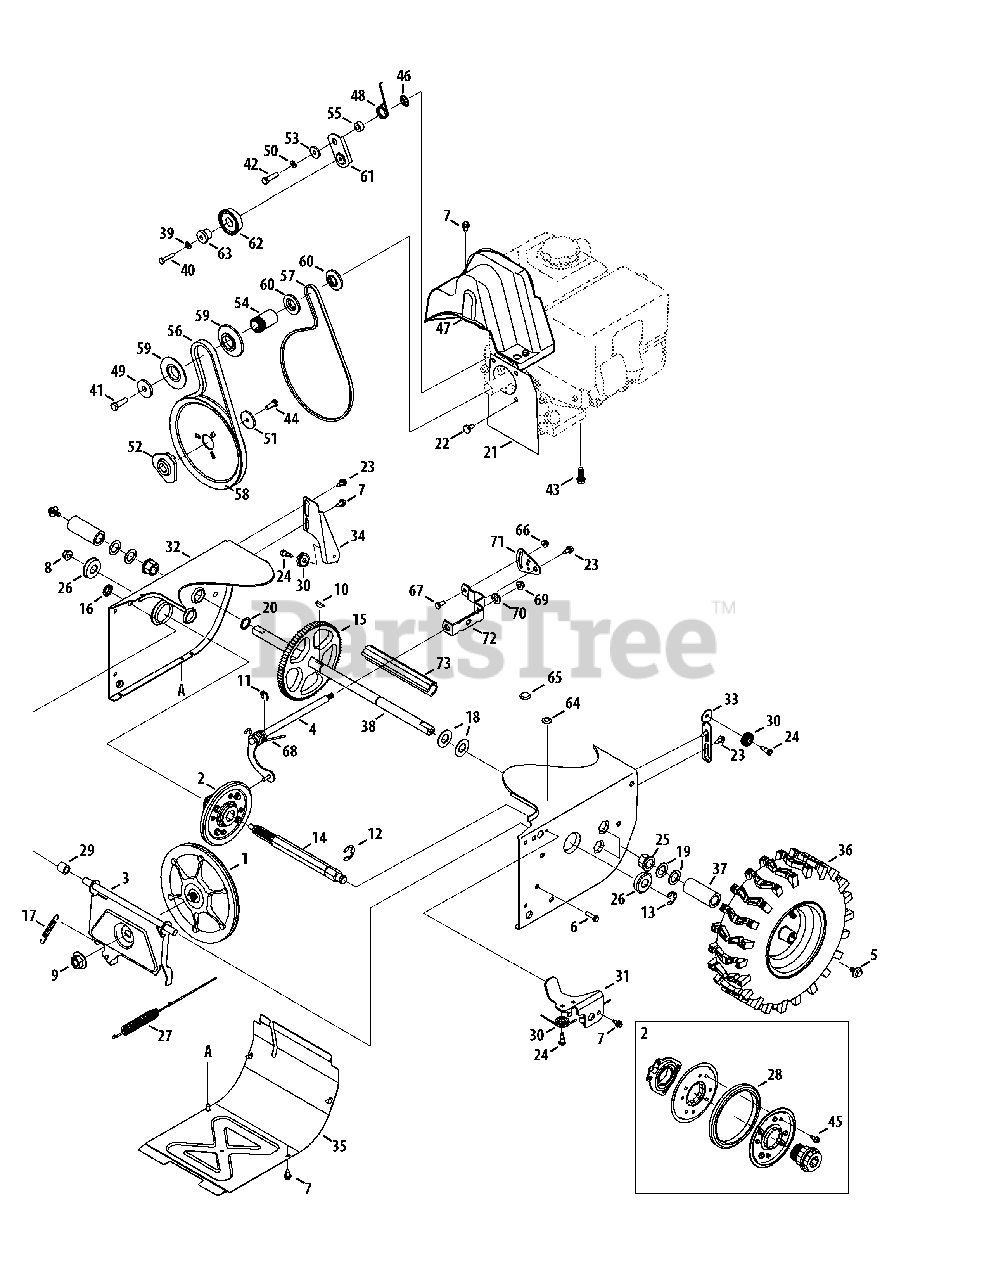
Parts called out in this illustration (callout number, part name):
1	Disc Assembly, Friction Wheel
2	Friction Wheel Assembly, 5.5 OD
3	Support Bracket, Friction Wheel
4	Shift Assembly, Rod
5	Screw, 5/16-24, .750, Gr5
6	Screw, 1/4-20, 1.000
7	Screw, 1/4-20 x .625
8	Nut, Flange Lock, 3/8-16, Nylon
9	Nut, Flange, 5/8-18
10	Key, Hi Pro, 3/16 x 3/4 Dia.
11	E-ring, .500 Dia.
12	E-ring, Retaining, .875 Dia.
13	E-ring, .750 Dia.
14	Hex Shaft, .8125, 7-Tooth
15	Gear, 80-Tooth
16	Speed Nut, .500
17	Extension Spring
18	Washer, Flat, .760 x 1.490 x .060
19	Washer, Flat, .793 x 1.24 x .060
20	Washer, Flat, .75 x 1.00 x .060
21	Plate, Cover
22	Shoulder Screw
23	Screw, Shoulder, .37 x .105, 1/4-20
24	Screw, 1/4-28, .375
25	Bearing, Hex Flange x .75 ID
26	Bearing, Ball, 17 x 40 x 12
27	Clutch Cable, Wheel, 44.95"
28	Rubber, Friction Wheel, 5.5 OD
29	Spacer, .508 ID x .75 OD x .68
30	Roller, Cable
31	Front Guide Bracket, Auger Cable
32	Frame
33	Guide Bracket, Auger Cable
34	Guide Bracket, Drive Cable
35	Cover, Frame
36	LH Wheel Assembly
36	RH Wheel Assembly
37	Spacer, 1.25 x .75 x 3.0
38	Axle, .75 x 22"
39	Washer, Lock, 1/4
40	Hex Screw, 1/4-20, 1.25, Gr5
41	Hex Screw, 3/8-24, 1.25, Gr8
42	Hex Screw, 5/16-24, 1.25, Gr5
43	Screw, Sems, 3/8-16, 1.00
44	Hex Screw, 5/16-24, .875, Gr8
45	Screw, 5/16-18 x .750
46	Nut, Push-on, .25 Dia.
47	Cover, Belt
48	Spring, Torsion, .850 ID x .354
49	Washer, Flat, .45 x 1.5 x .172
50	Washer, Lock .3125
51	Washer, Flat, .34 x 1.50 x .150
52	Pulley, Adapter, .75 Dia.
53	Spacer, Shoulder, .317 x .50 x .102
54	Spacer, .875 ID x 1.185 OD
55	Spacer, .340 x .750 x .360
56	Belt, Auger Drive
57	Belt, Wheel Drive
58	Pulley, Auger Drive, 8.1 x .5
59	Pulley, Half, V x 2.600 OD
60	Pulley, Half, 3/8-V x 1.7160 OD
61	Idler Bracket, Wheel Drive
62	Idler Pulley Assembly
63	Spacer, Shoulder, .26 x .79 x .538
64	Plug, 3/8 ID
65	Plug, 1/2 ID
66	Nut, Flange Lock, 1/4-20, Nylon
67	Hex Screw, 1/4-20, .620, Gr5
68	Spring, Torsion, .750 ID x .968
69	Nut, Flange Lock, 5/16-18, Nylon
70	Wash., Flat, .469 x .875 x .105
71	Pivot Bracket, Speed Selector
72	Shift Bracket, Speed Selector
73	Spacer, Axle
